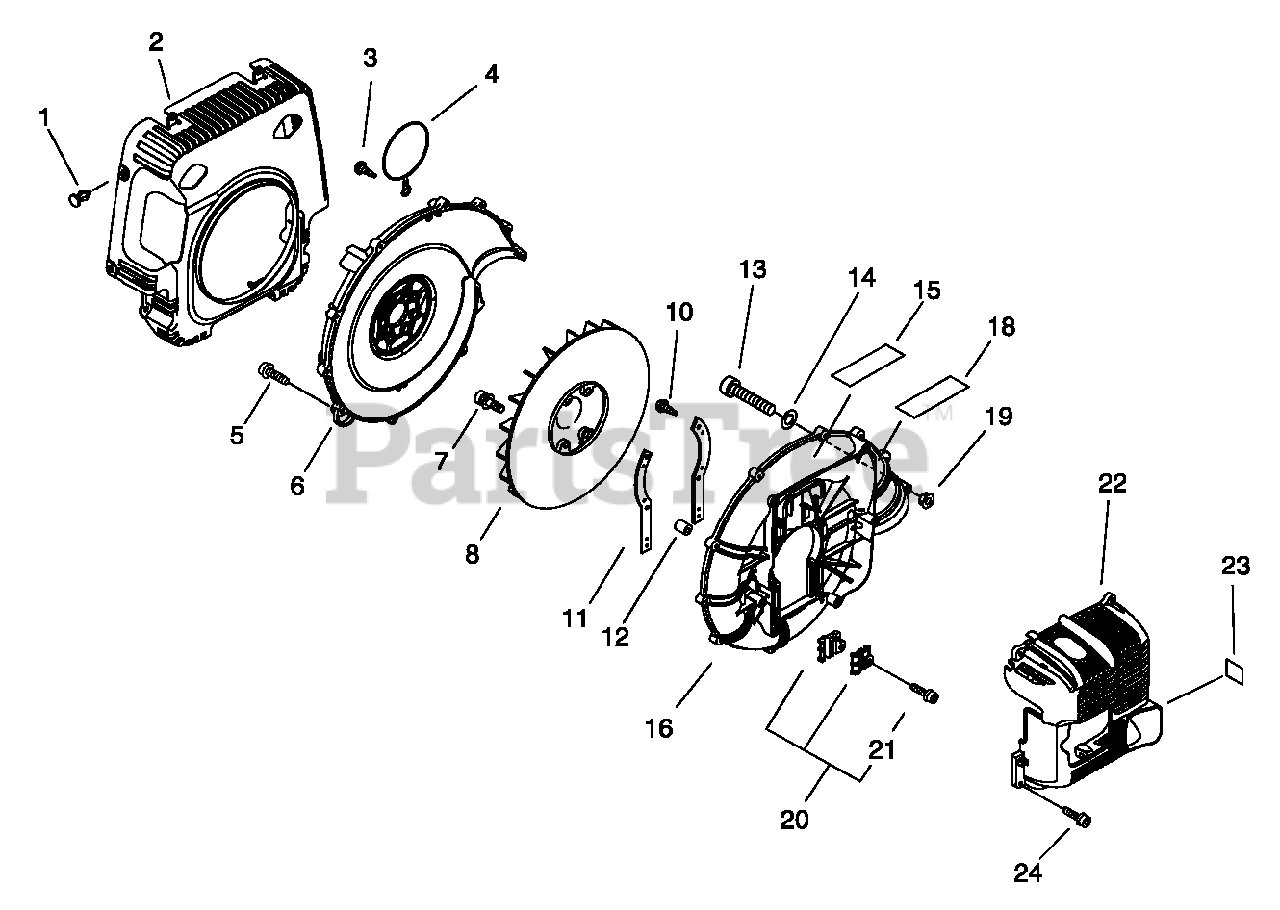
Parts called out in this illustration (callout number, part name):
2	GUARD, DEBRIS
3	SCREW TAPPING 5×16
4	STRAP, SAFETY
5	BOLT, TAPPING 5×25
6	COVER, FAN
7	BOLT 5×20
10	SCREW TAPPING 3×12
11	BRACKET, ENGINE
12	COLLAR
13	BOLT 5×60
14	WASHER, FLAT 5.5×10×0.8
15	LABEL, MODEL
16	CASE, FAN
18	LABEL, CAUTION - ISO
19	NUT, FLANGE M5
20	BRACKET KIT, CABLE
21	BOLT, TAPPING 5×25
22	COVER, ENGINE
23	LABEL, CAUTION - HOT
24	SCREW TAPPING 5×20
